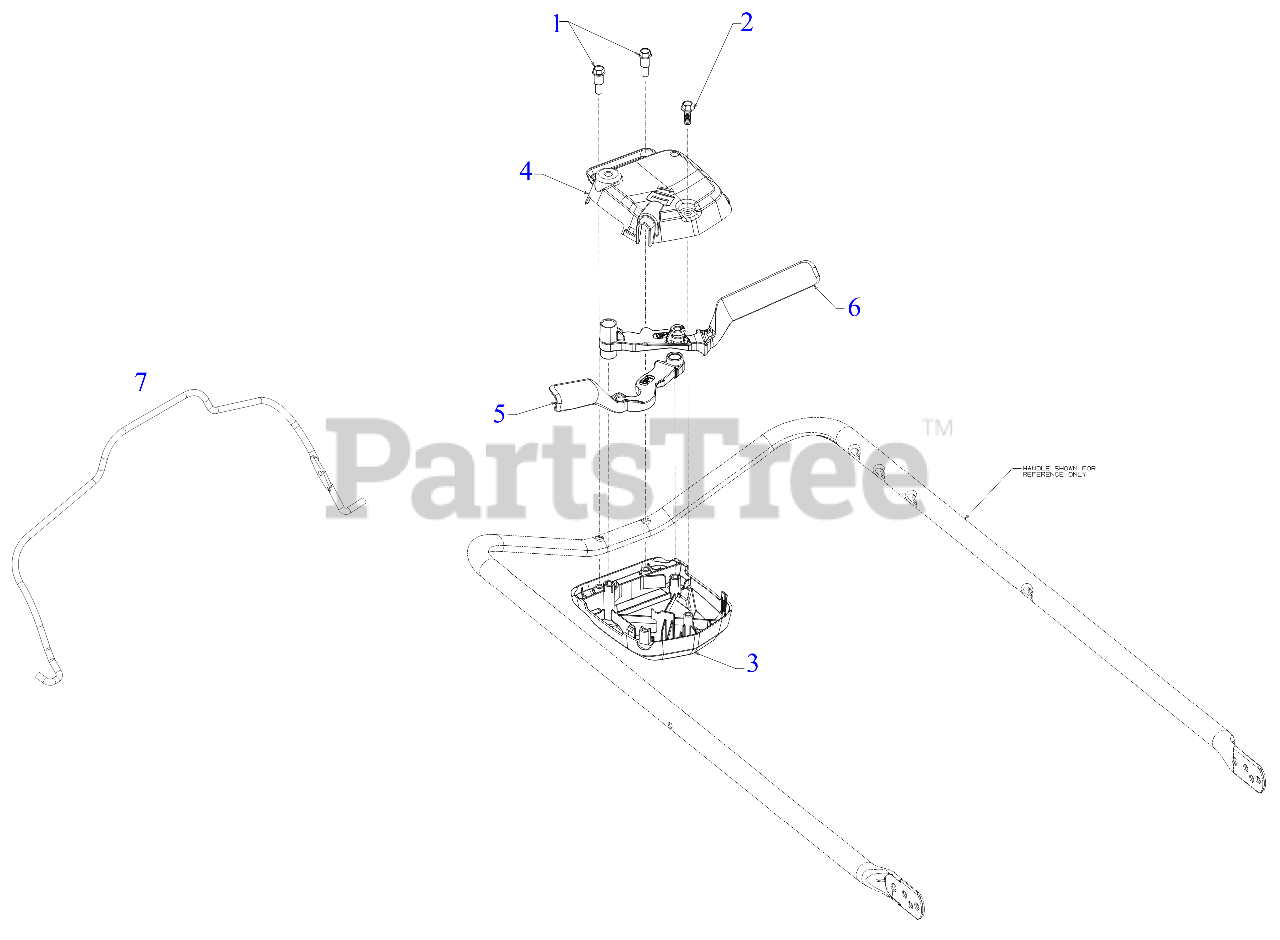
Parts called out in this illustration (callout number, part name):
1	SHOULDER SCREW 1/4-15 x .970
2	SCREW 1/4-15 x .750
3	UPPER CONTROL HOUSING
4	LOWER CONTROL HOUSING
5	CONTROL LEVER (LH) (SBD GRAY)
6	CONTROL LEVER (RH) (SBD GRAY)
7	OPERATOR BAIL (LIBERTY RED)
